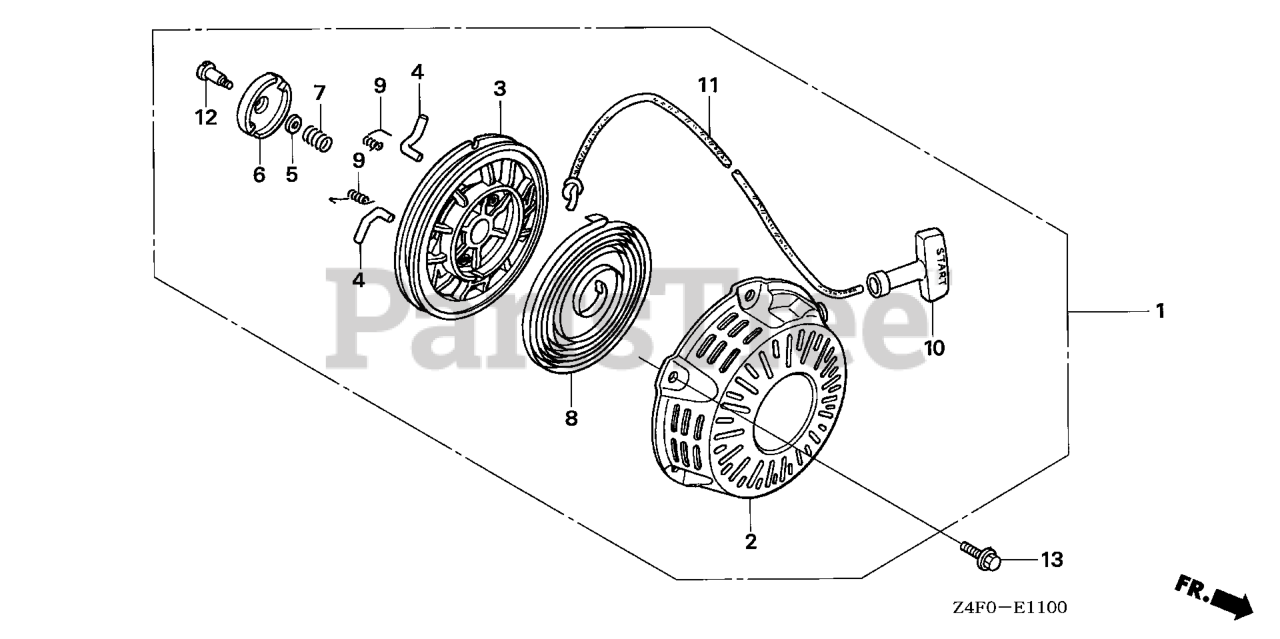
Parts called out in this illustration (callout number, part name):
1	STARTER ASSY., RECOIL *NH1* (BLACK)
2	CASE, RECOIL STARTER *NH1* (Honda Code 4193058). (BLACK)
3	REEL, RECOIL STARTER
3	REEL, RECOIL STARTER (BLACK)
4	RATCHET, STARTER
5	PLATE, FRICTION
6	GUIDE, RATCHET
7	SPRING, FRICTION
8	SPRING, RECOIL STARTER
9	SPRING, RETURN
10	GRIP, STARTER
11	ROPE, RECOIL STARTER (#5X55")
12	SCREW, SETTING
13	BOLT, FLANGE (6X10)
